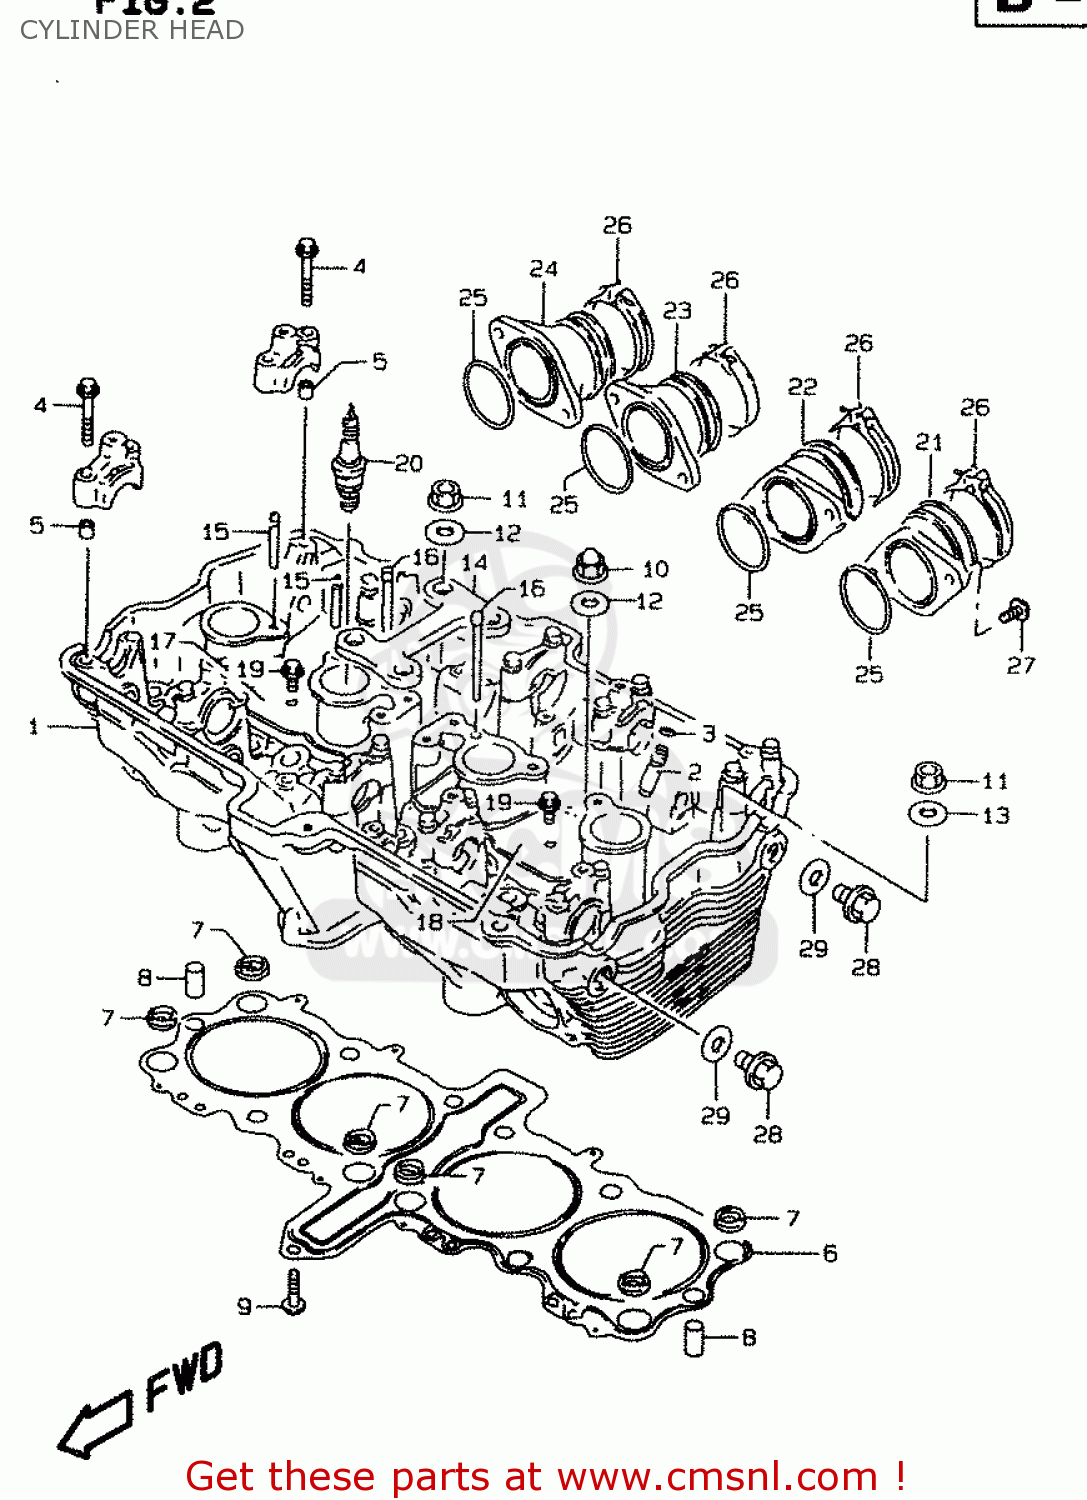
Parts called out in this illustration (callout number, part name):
1	HEAD ASSY,CYLINDER
2	GUIDE,VALVE
3	RING,SNAP
4	BOLT(6X39)
5	PIN(6.2X8X11)
6	GASKET,CYLINDER HEAD
7	O-RING,HEAD GASKET
8	PIN
9	BOLT
10	NUT
11	NUT
12	GASKET(10.2X20X2).3 (NAS)
13	WASHER (10.5X22X2.3)
14	PLATE,HEAD REINFORCEMENT
15	PIPE,OIL NO.1
16	PIPE,OIL NO.3
17	PLATE,OIL PIPE,R
18	PLATE,OIL PIPE,L
19	BOLT
20	PLUG,SPARK(JR9B)
21	PIPE,INTAKE NO.1
22	PIPE,INTAKE NO.2
23	PIPE,INTAKE NO.3
24	PIPE,INTAKE NO.4
25	O RING(D:2.4,ID:39.7)
26	CLAMP
27	BOLT MAGNETO S
28	PLUG
29	GASKET(13.8X18.8X4.8) (NAS)
